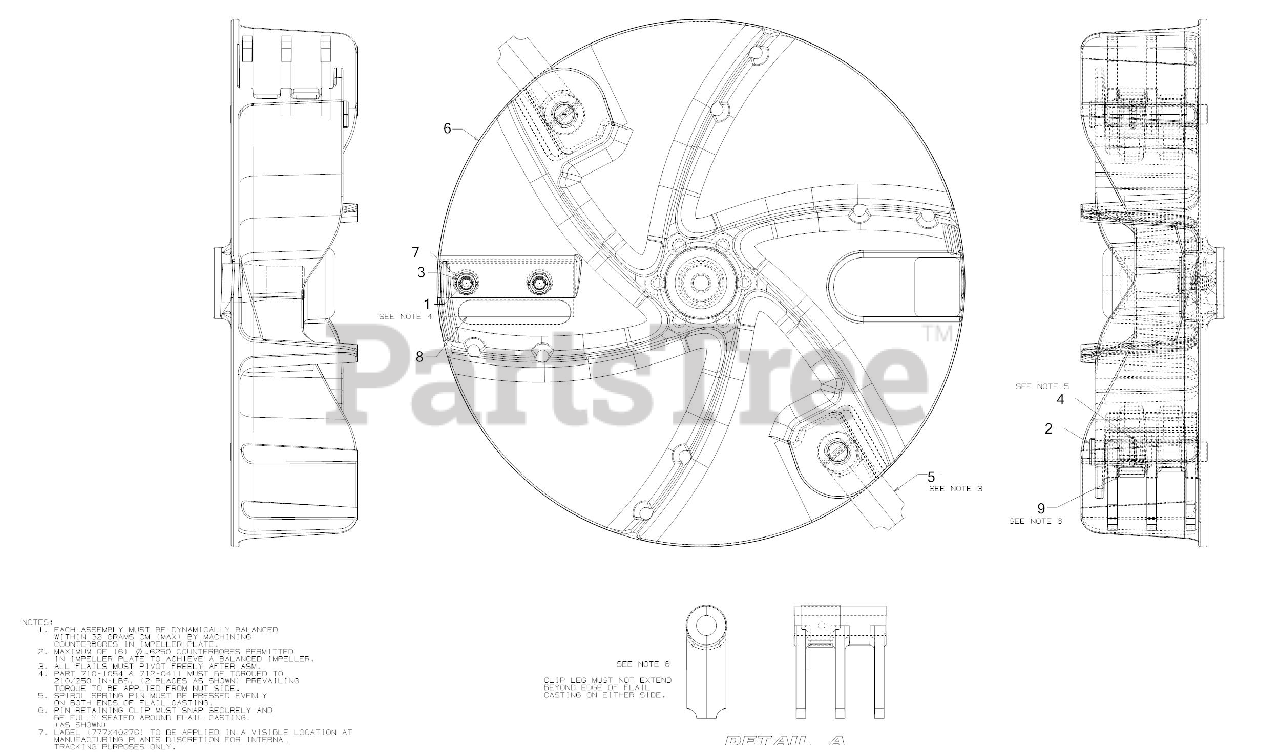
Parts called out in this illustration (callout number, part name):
1	SCREW 5/16-24 x 1
2	CLEVIS PIN DIA .49
3	HEX NUT
4	PIN SPIROL .156X1
5	FLAIL BLADE
6	IMPELLER ASSEMBLY
7	LOCK WASHER 5/16
8	CHIPPER BLADE
9	RETAINING PIN CLIP
